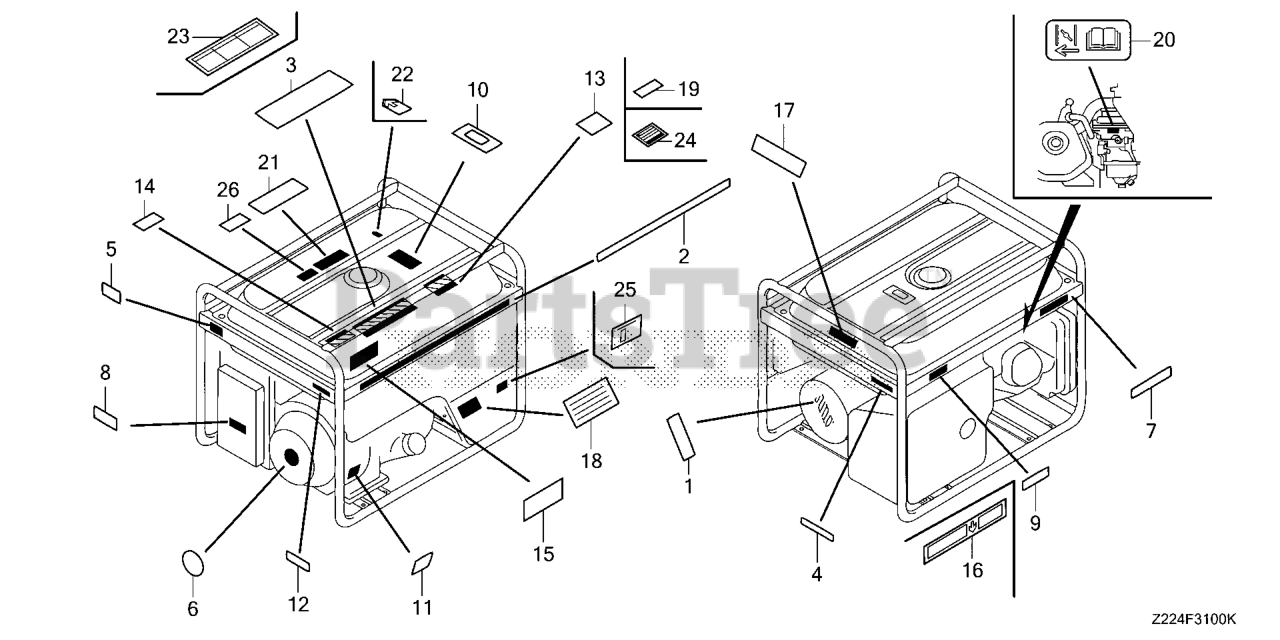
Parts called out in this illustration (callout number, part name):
1	MARK, VOLT
2	MARK, EMBLEM (EB5000X)
3	MARK, CAUTION (E)
5	MARK, CHOKE
6	MARK, HONDA
7	MARK, HONDA
9	MARK, EX. CAUTION
10	PLATE, FUEL INDICATION
11	MARK, OIL CHECK
13	MARK, CPSC (CO CAUTION)
